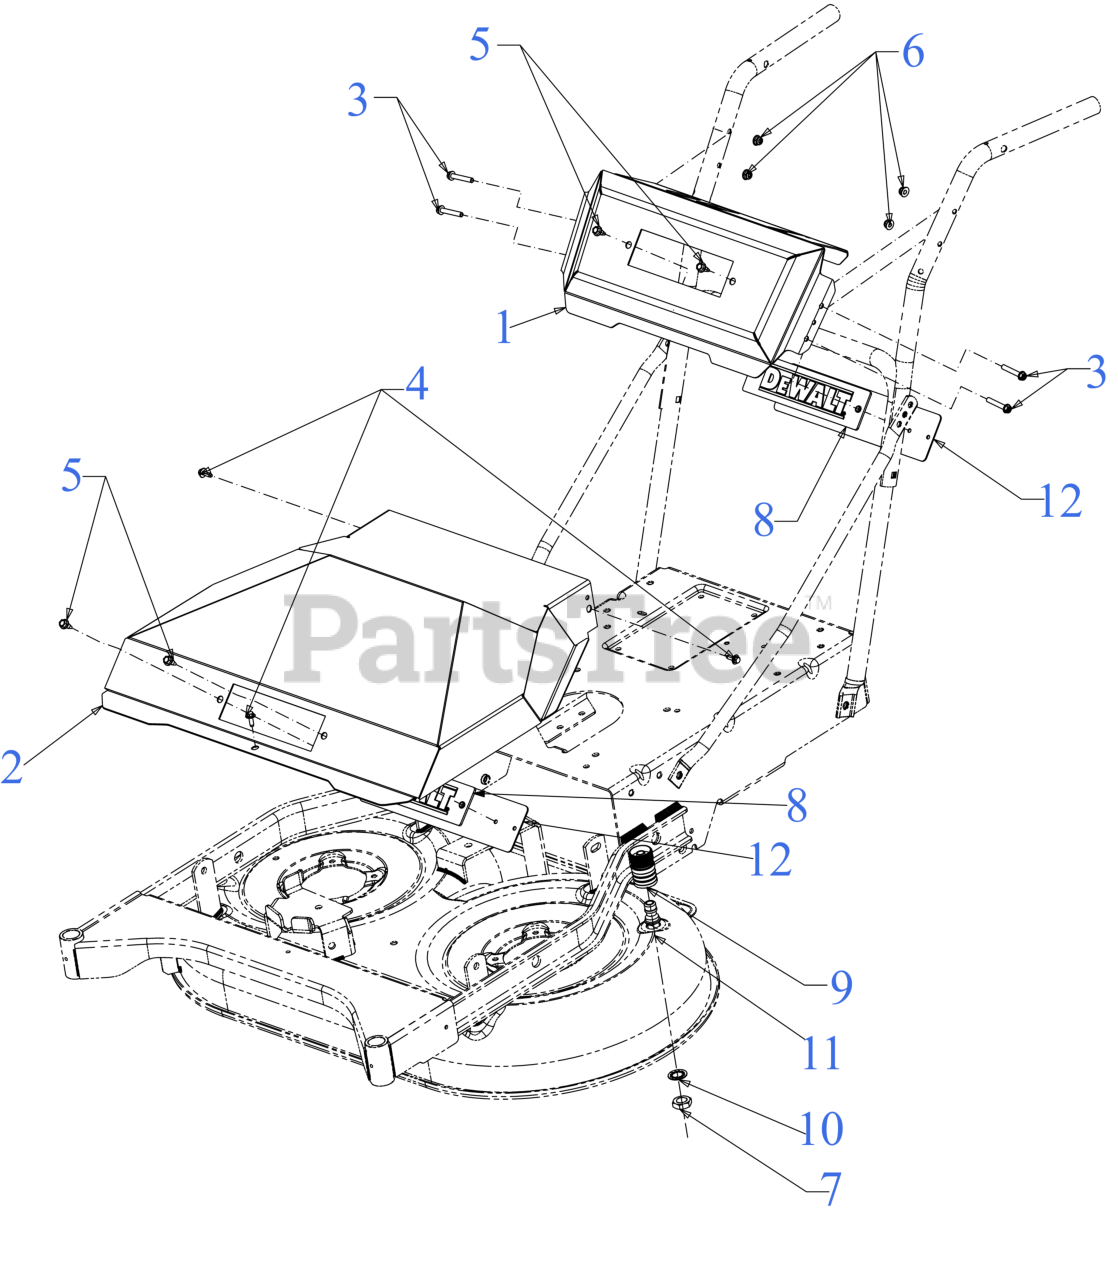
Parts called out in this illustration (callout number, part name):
1	HANDLE PANEL
2	BELT COVER
3	HEX FLANGE BOLT 1/4-20 x 1.5
4	SCREW M6-1 x .625
5	SCREW 1/4-20X.625
6	FLANGE LOCK NUT
7	HEX NUT
8	DEWALT LOGO (DIE CAST)
9	WATER NOZZLE ADAPTER
10	LOCK WASHER 5/8
11	DECK WASH NOZZLE
12	LOGO BACK PLATE
